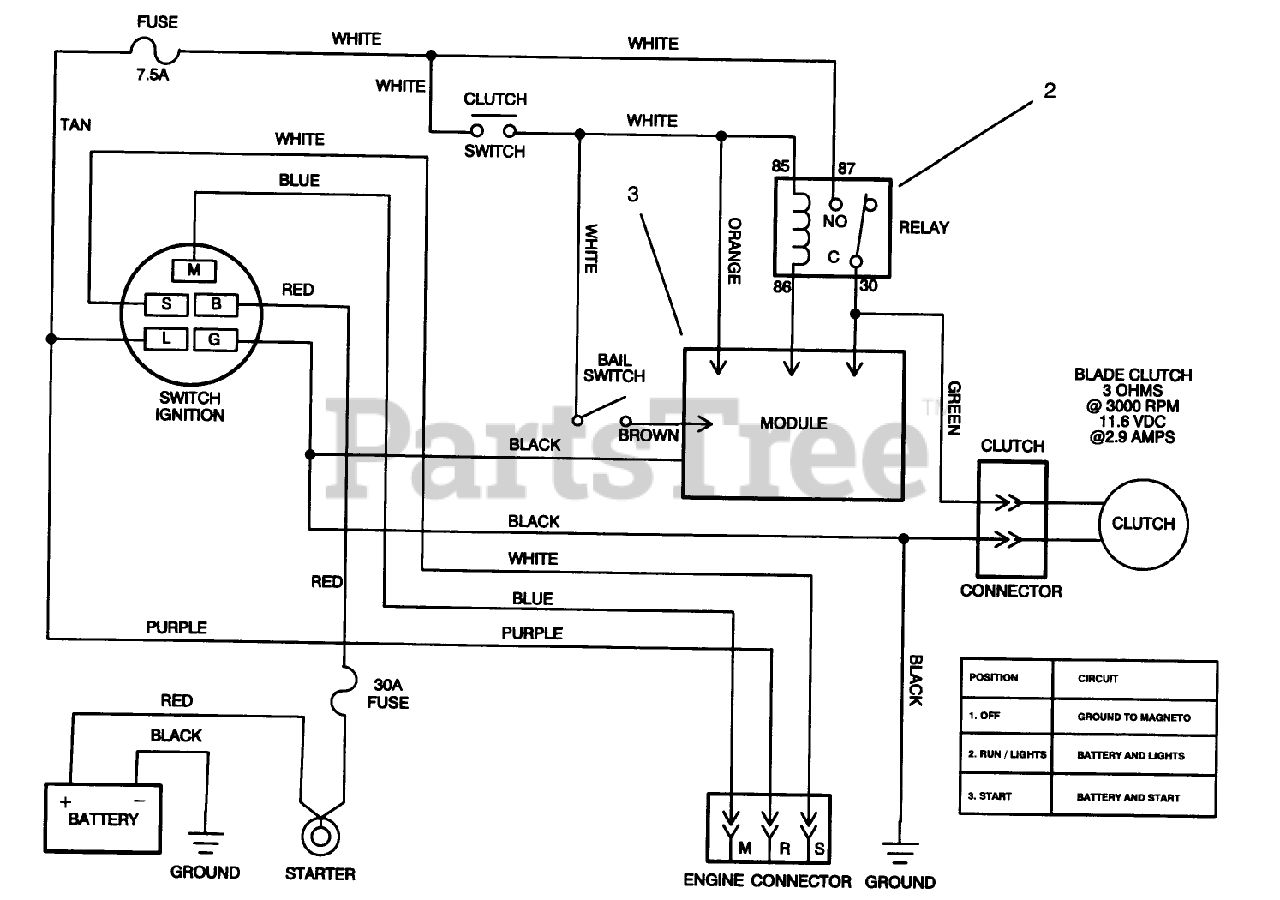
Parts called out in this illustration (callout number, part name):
1	WIRE HARNESS-18HP ELECT.
2	RELAY
3	Module
